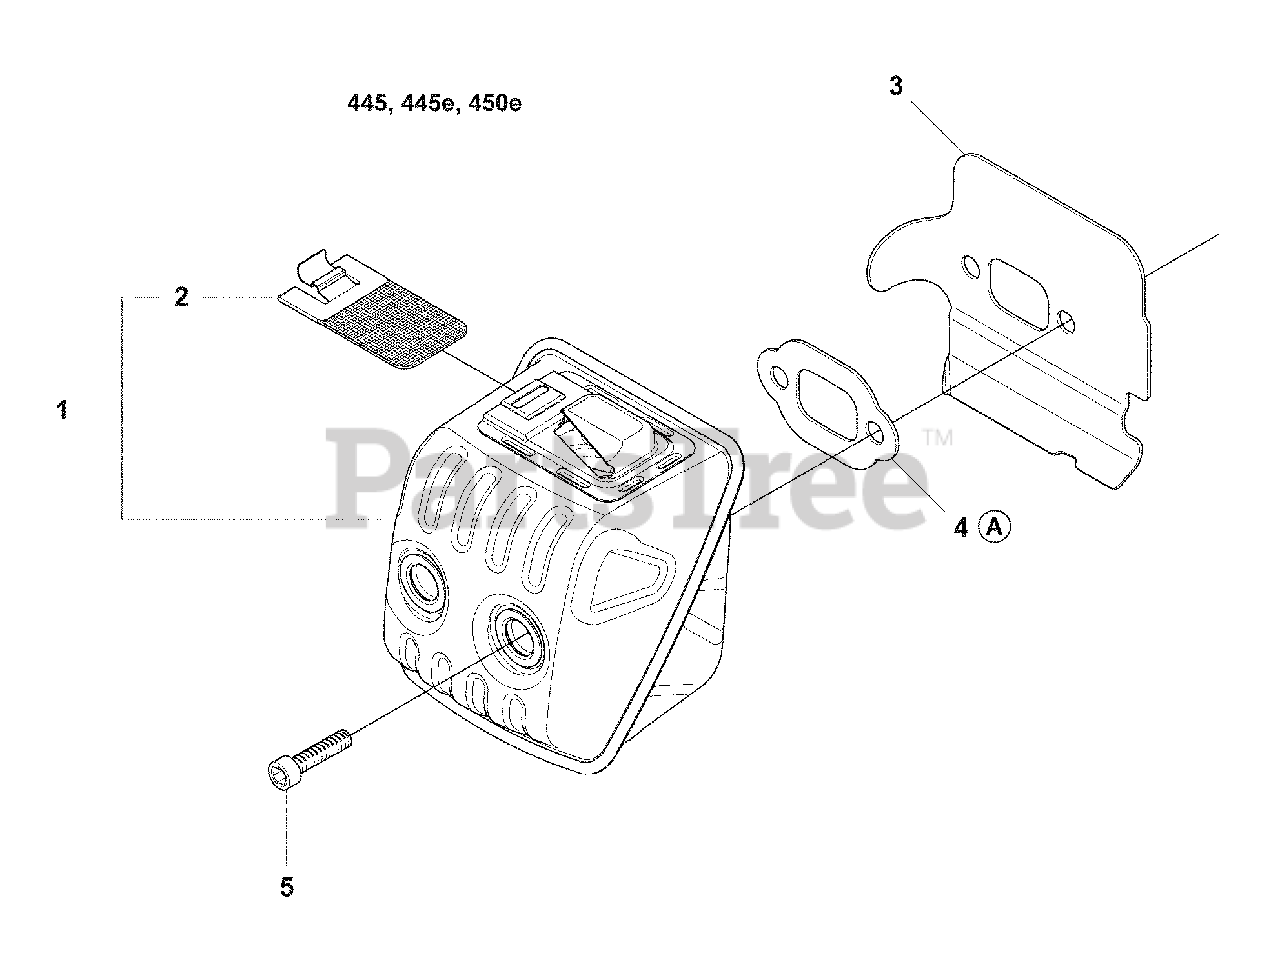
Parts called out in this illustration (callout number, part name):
1	Muffler Assembly
2	Spark Arrester
3	Heat Deflector
4	Gasket
5	Screw, IHSCM
